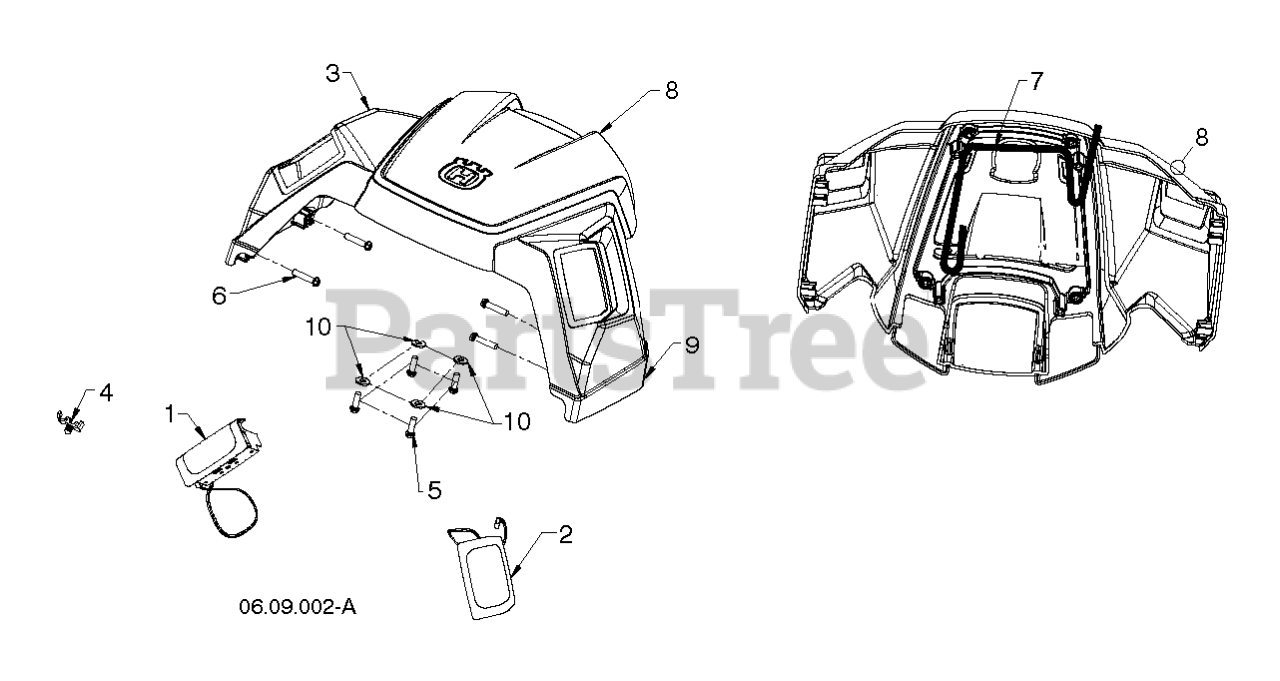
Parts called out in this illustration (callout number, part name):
1	LIGHT.LED.RH.SUBASM 12
2	LIGHT.LED.LH.SUBASM 12
3	CONTROL.SHROUD.SNOW
5	SCREW.HX.13X.750
6	SCREW.HWH.13-16X1.12
7	HARNESS.LED
8	SUBASM.CONTROL.SHROUD
9	COVER.HANDLE.LG.SHROUD
